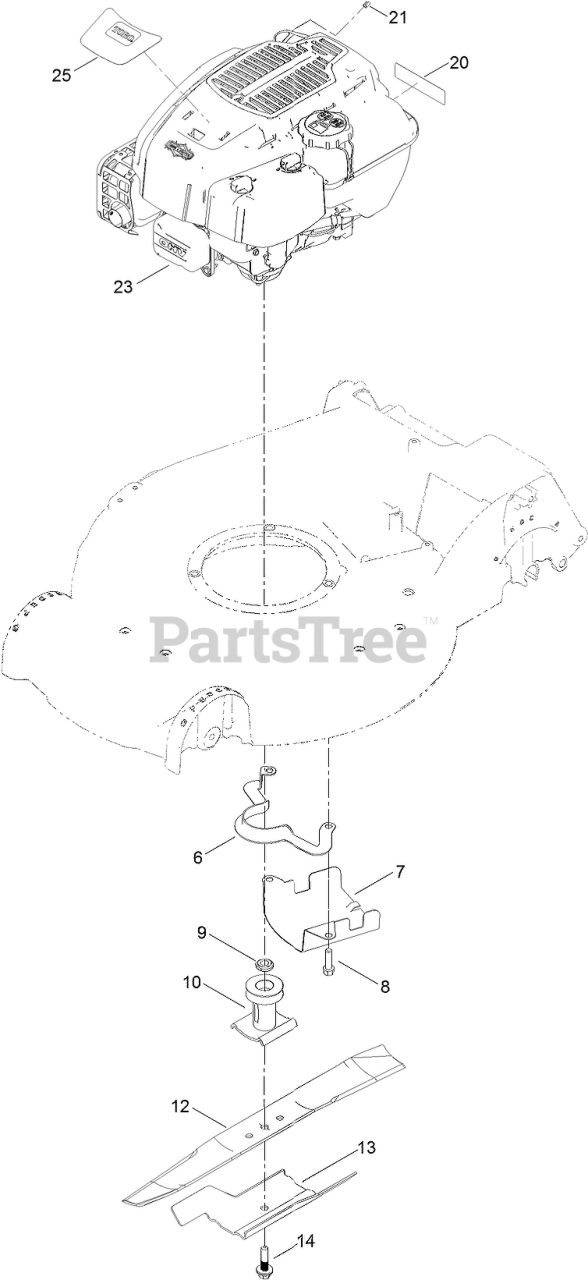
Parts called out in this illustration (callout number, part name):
6	GUIDE-BELT
7	SHIELD-GRASS
8	SCREW-TAPTITE
9	SPACER-DRIVER
10	DRIVER-BLADE
12	BLADE-21IN, RECYCLING
13	ACCELERATOR-BLADE
14	BOLT-BLADE
20	DECAL-ARRESTOR, SPARK
21	STOP-ROPE
23	ENGINE-BRIGGS 875 ES SS
25	DECAL-ENGINE
